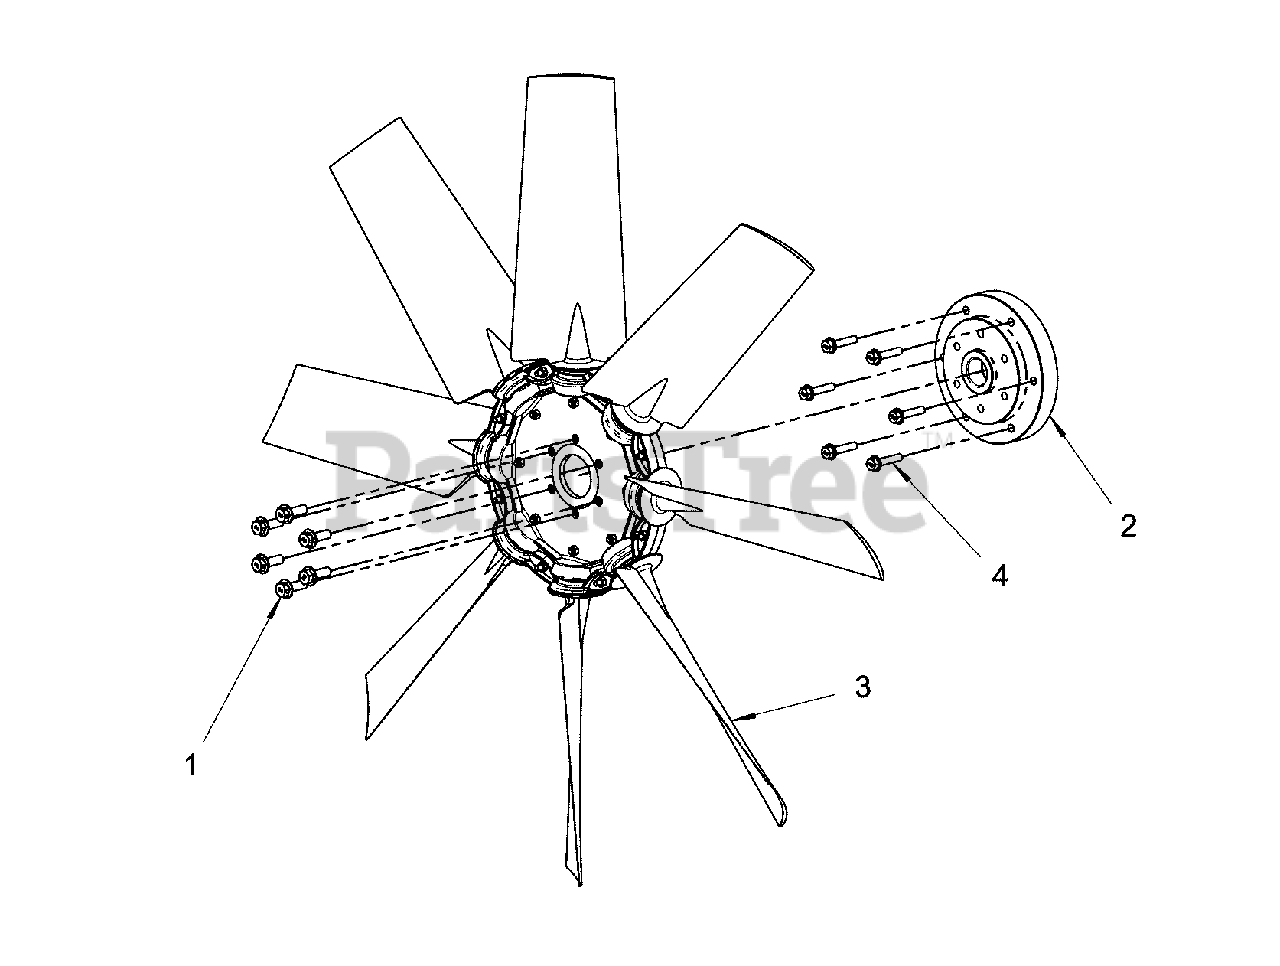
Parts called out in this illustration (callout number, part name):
1	* BOLT
2	* SPACER
3	FAN PUSHER
4	* BOLT
